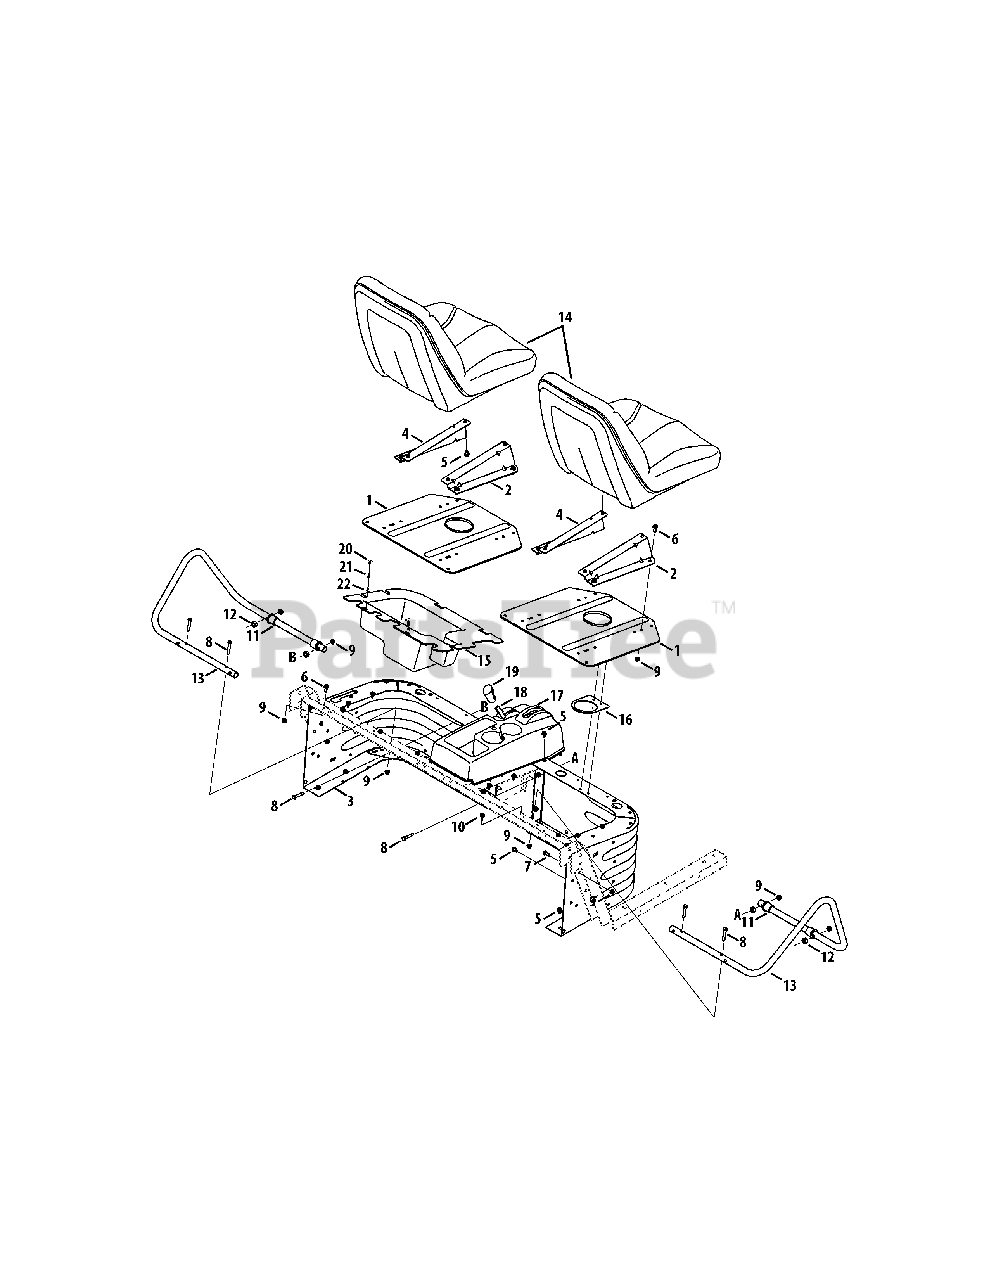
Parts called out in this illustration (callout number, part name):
1	Plate, Seat, Assembly
5	Screw, TT, 5/16-18 x .500
6	Screw, LD, 5/16-18 x .750
7	Screw, 5/16-18 x .75
8	Screw, 5/16-18 x 1.75
9	Nut, Flange Lock, 5/16-18
10	Bumper, .62 Dia. x .3
11	Bearing, Flange, .894 ID x 1.1315
12	Spacer, .315 x .750 x .375 Lg.
14	Seat, High Back
14	Seat, Sport
15	Tray, Seat Box
16	Bracket, Tube, CVT
17	Seat Console
17	Cover, Bench Seat
18	Lever Assembly, Diff Lock
18	Lever Ass’y, Diff Lock, Bench Seat
19	Handle, Select
21	Spring Clip
22	Spring, .40 OD x .040 Dia.
